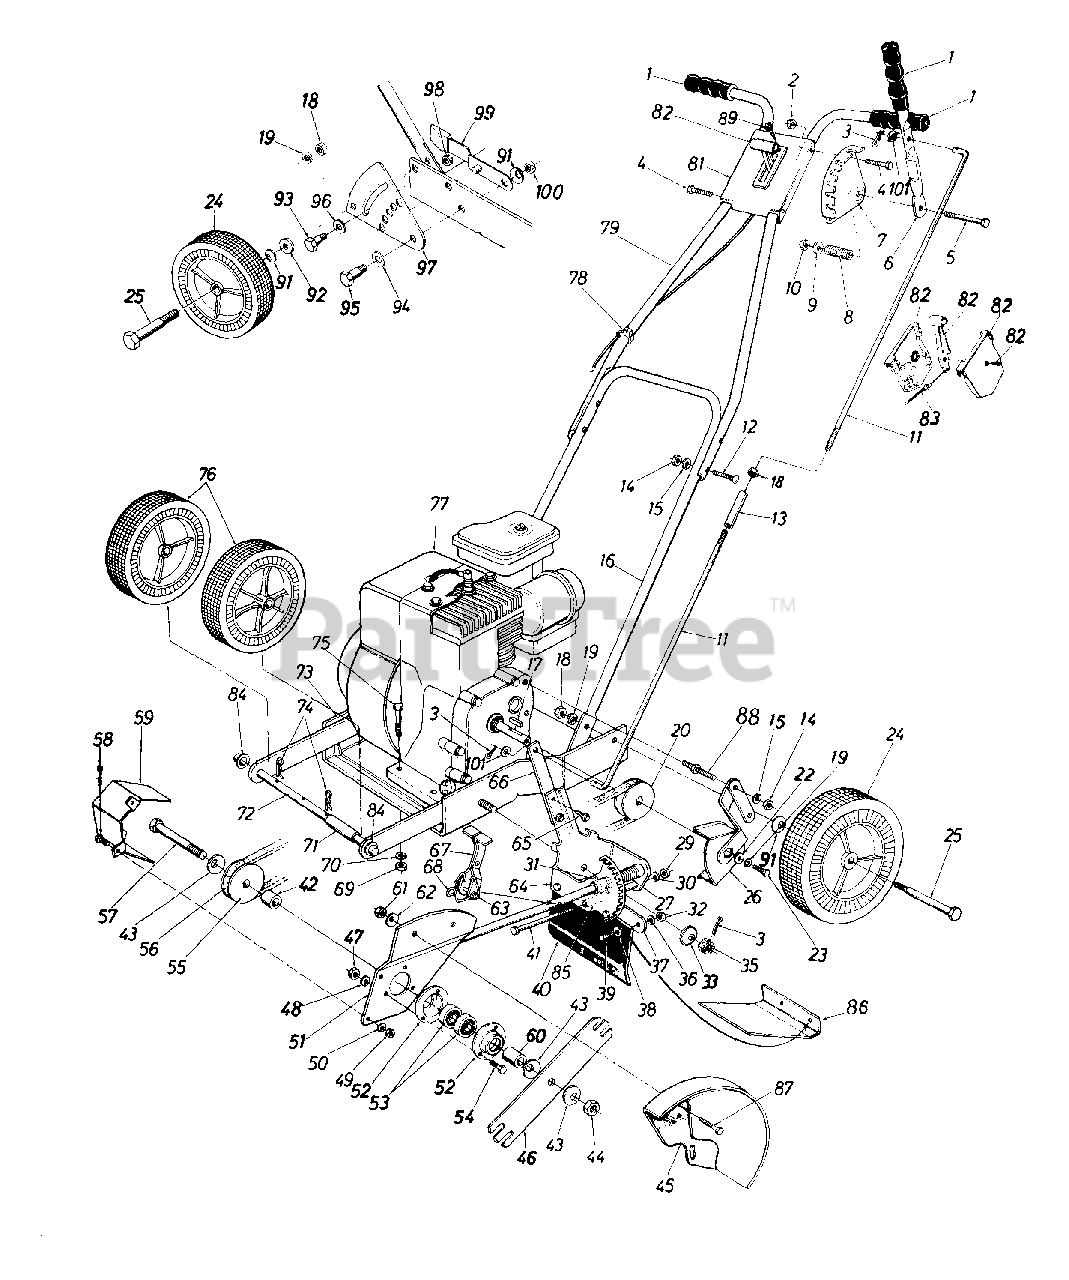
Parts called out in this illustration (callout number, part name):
1	Black Grip
2	Hex L-Nut 1/4-20 Thd.
3	Cotter Pin 1/8" Dia.
4	Hex Bolt 1/4-20 x 1.25" Lg.
5	Hex Bolt 5/16-18 x 2" Lg.
8	Compression Spring 1.38" Lg.
9	Fl-Wash. .344" I.D.
10	Hex L-Nut 5/16-18 Thd.
11	Clutch Rod Half 18.25" Lg.
12	Carriage Bolt 1/4-20 x 1.25" Lg.
13	Rod Adjustment Link
14	Hex Nut 1/4-20 Thd.
15	L-Wash. 1/4" I.D.
16	Lower Handle (Painted)
17	Sq. Key 3/16" x .75" Lg.
18	Hex Nut 3/8-16 Thd.
19	L-Wash. 3/8" I.D.
20	Engine Pulley
22	Fl-Wash. .385" I.D.
23	Hex Bolt 3/8-24 x 1" Lg.
24	Rear Wheel Ass'y. 8" x 1.75"
25	Shoulder Bolt .498" Dia.
29	Hex Nut 5/16-18 Thd.
30	L-Wash. 5/16" I.D.
31	Spring Pin Spir. 3/16" Dia.
32	Hex Nut 1/4-20 Thd.
33	Bell-Wash. .535" I.D.
35	Hex Slotted Nut 1/2-20 Thd.
36	L-Wash. 1/4" I.D.
39	Hex Bolt 1/4-20 x .50" Lg.
41	Hex Bolt 5/16-18 x 4.5" Lg.
42	Spacer 1.030" Lg.
43	Bell-Washer. .63" I.D.
44	Hex Jam L-Nut 5/8-18 Thd.
47	Hex Nut 1/4-20 Thd.
48	L-Wash. 1/4" I.D.
49	Hex Nut 1/4-20 Thd.
50	L-Wash. 1/4" I.D.
53	Ball Bearing .62" I.D.
54	Hex Bolt 1/4-20 x .62" Lg.
55	3/8" "V"-Pulley
56	"V"-Belt
57	Hex Bolt 5/8-18 x 4.5" Lg.
58	Hex Bolt 1/4-20 x .625" Lg.
60	Sleeve .90" Lg.
61	Hex Nut 5/16-18 Thd.
62	Bell-Wash. .345" I.D.
63	Spring Pin Spir. 1/4" Dia.
68	Torsion Spring
69	Hex Nut 5/16-18 Thd.
70	L-Wash. 5/16" I.D.
71	Spacer 1.62" Lg.
72	Axle 8.75" Lg. (Front)
73	Base Ass'y.
74	Hairpin Cotter 1/2" Dia.
75	Hex Bolt 5/16-18 x 1.5" Lg.
76	Front Wheel Ass'y. 7" x 1.50"
77	Engine
78	Cable Tie
79	Upper Handle (Painted)
83	Throttle Control Wire 30" Lg.
84	Push Cap 1/2" Dia.
85	Spacer 3.765" Lg.
88	Stud 1/4-20 x 2.12" Lg.
89	Self-Tap Scr. #10 x .50" Lg.
91	Bell-Wash. .40" I.D.
92	Fl-Wash. .39" I.D.
93	Shld. Bolt .5" Dia.
94	Bell-Wash. .515" I.D.
95	Shld. Bolt .50" Dia.
96	Fl-Wash. .51" I.D. x .94"
99	Spring Adj. Lever
100	Hex Jam Nut 3/8-16 Thd.
101	Fl-Wash. 3/8" I.D.
